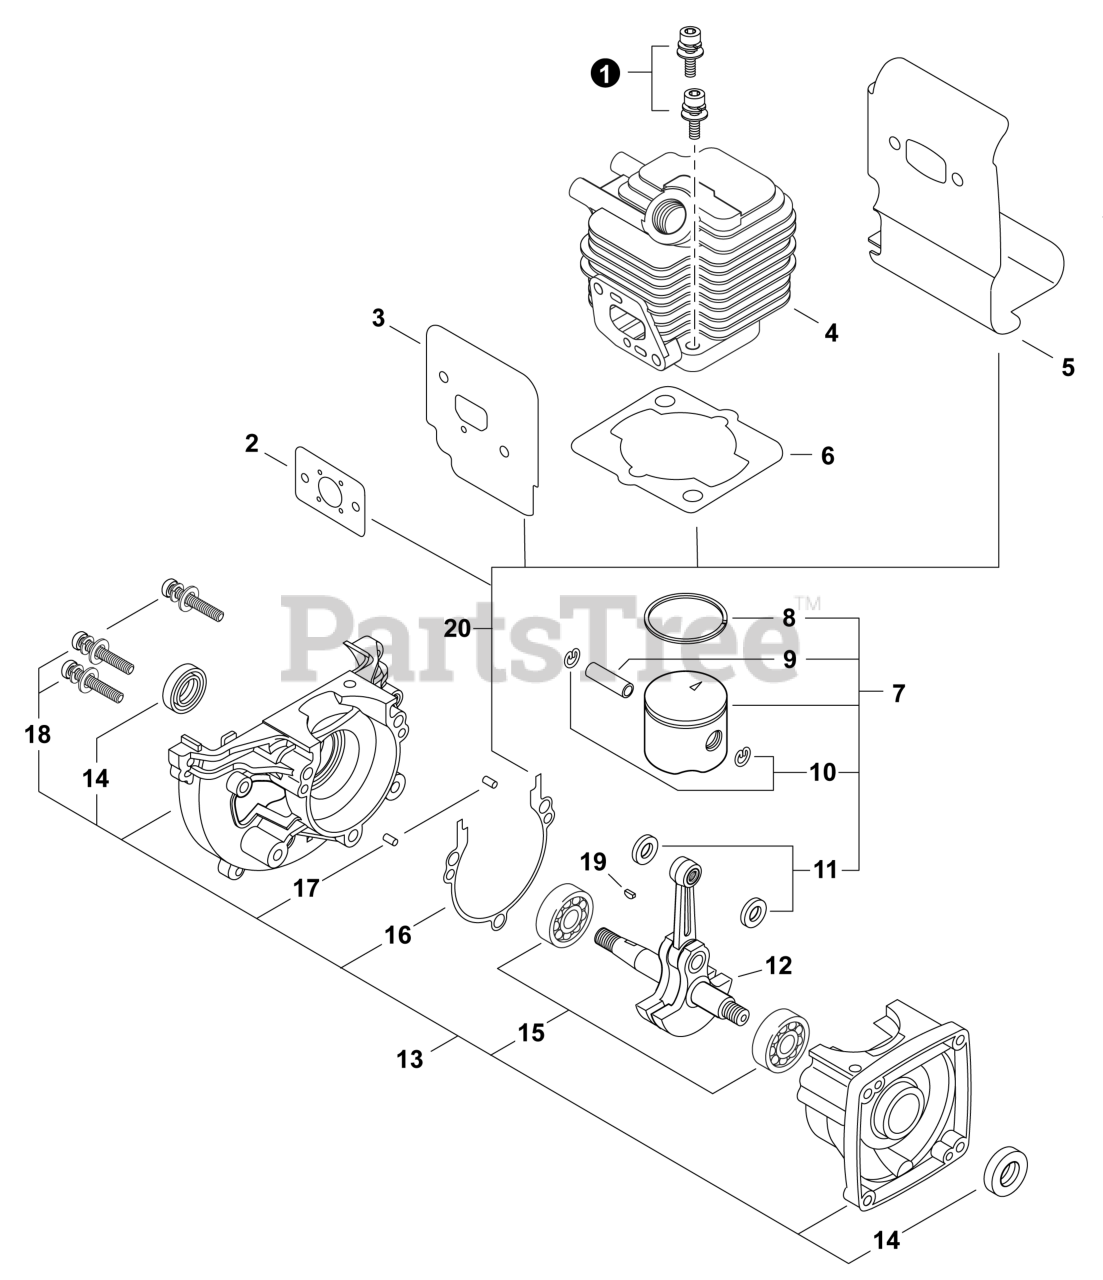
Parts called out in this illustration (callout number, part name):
1	BOLT 5x22
2	GASKET, INTAKE
3	HEAT SHIELD, INTAKE
4	CYLINDER
5	HEAT SHIELD, EXHAUST
6	GASKET, CYLINDER
7	PISTON KIT
8	RING, PISTON
9	PIN, PISTON 8
10	RING, SNAP
11	WASHER, THRUST
12	CRANKSHAFT ASSY
13	CRANKCASE KIT
14	SEAL, OIL 12
15	BEARING, BALL 6201
16	GASKET, CRANKCASE
17	PIN, LOCATING 4x8
18	BOLT 5x28
19	KEY, WOODRUFF
20	GASKET KIT: ENGINE, INTAKE, EXHAUST
